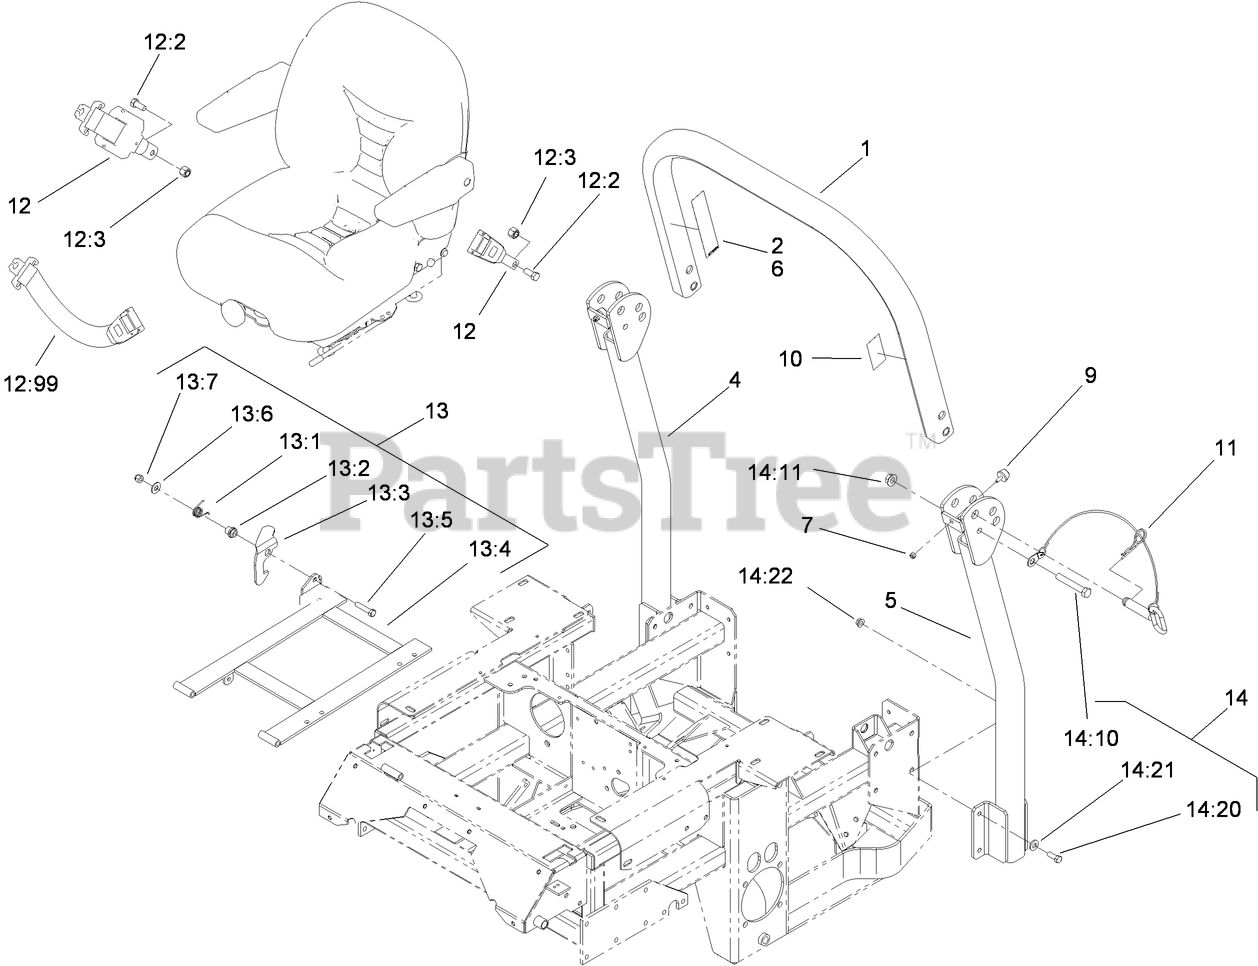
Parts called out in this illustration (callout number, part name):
1	Deck ASM
2	DECAL-WARNING, FOLDING ROPS
4	Deck ASM
5	Deck ASM
6	DECAL-WARNING
7	NUT-LOCK, NI
9	BUMPER-RUBBER
10	DECAL-ROPS
11	PIN-FOLD, ROPS
12	RETRACTABLE SEATBELT KIT
12:2	SCREW-HH
12:3	NUT-LOCK
12:99	SEAT BELT EXTENSION KIT
13	SEAT FRAME SINGLE LATCH ASM
13:1	CATCH-LATCH, SINGLE
13:2	SPRING-TORSION, LATCH
13:3	BUSHING-LATCH, SEAT
13:4	FRAME-SEAT
13:5	WASHER-FLAT
13:6	NUT-LOCK, NI
13:7	SCREW-HH
14	Deck ASM
14:10	SCREW-HH
14:11	NUT-HF
14:20	SCREW-HH
14:21	WASHER-BELLEVILLE
14:22	NUT-HHF, WHIZ
